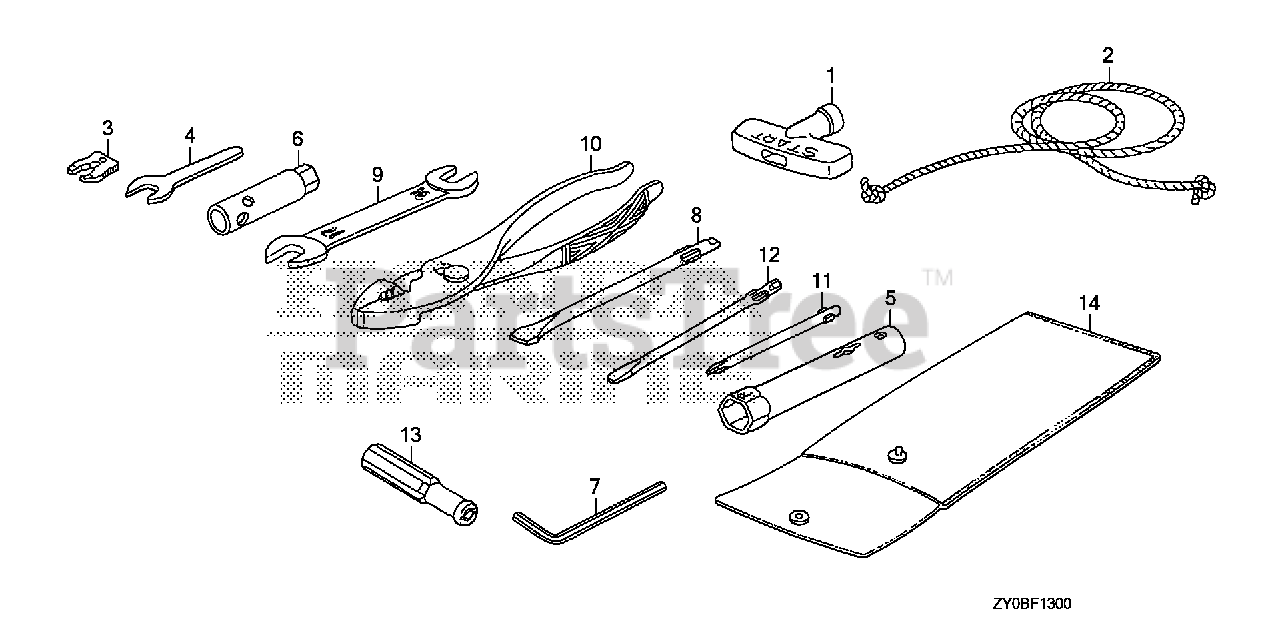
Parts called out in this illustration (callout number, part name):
1	KNOB, RECOIL STARTER
1	GRIP, STARTER
2	ROPE, RECOIL STARTER (1300MM)
3	CLIP, EMERGENCY LOCK
4	WRENCH (8MM) (OPEN END) (NOT AVAILABLE)
5	WRENCH, SPARK PLUG
6	WRENCH, BOX (10MM) (NOT AVAILABLE)
7	WRENCH, HEX. (4MM)
8	SCREWDRIVER, CHECK BOLT
9	WRENCH (10X12) (OPEN END)
10	PLIERS (135) (RIKEN)
10	PLIERS (135) (KOWA)
11	SCREWDRIVER 1, PHILLIPS (NO.2)
12	SCREWDRIVER 3, STRAIGHT SLOT (NO. 2)
13	GRIP, SCREW DRIVER
14	BAG, TOOL (160MM)
